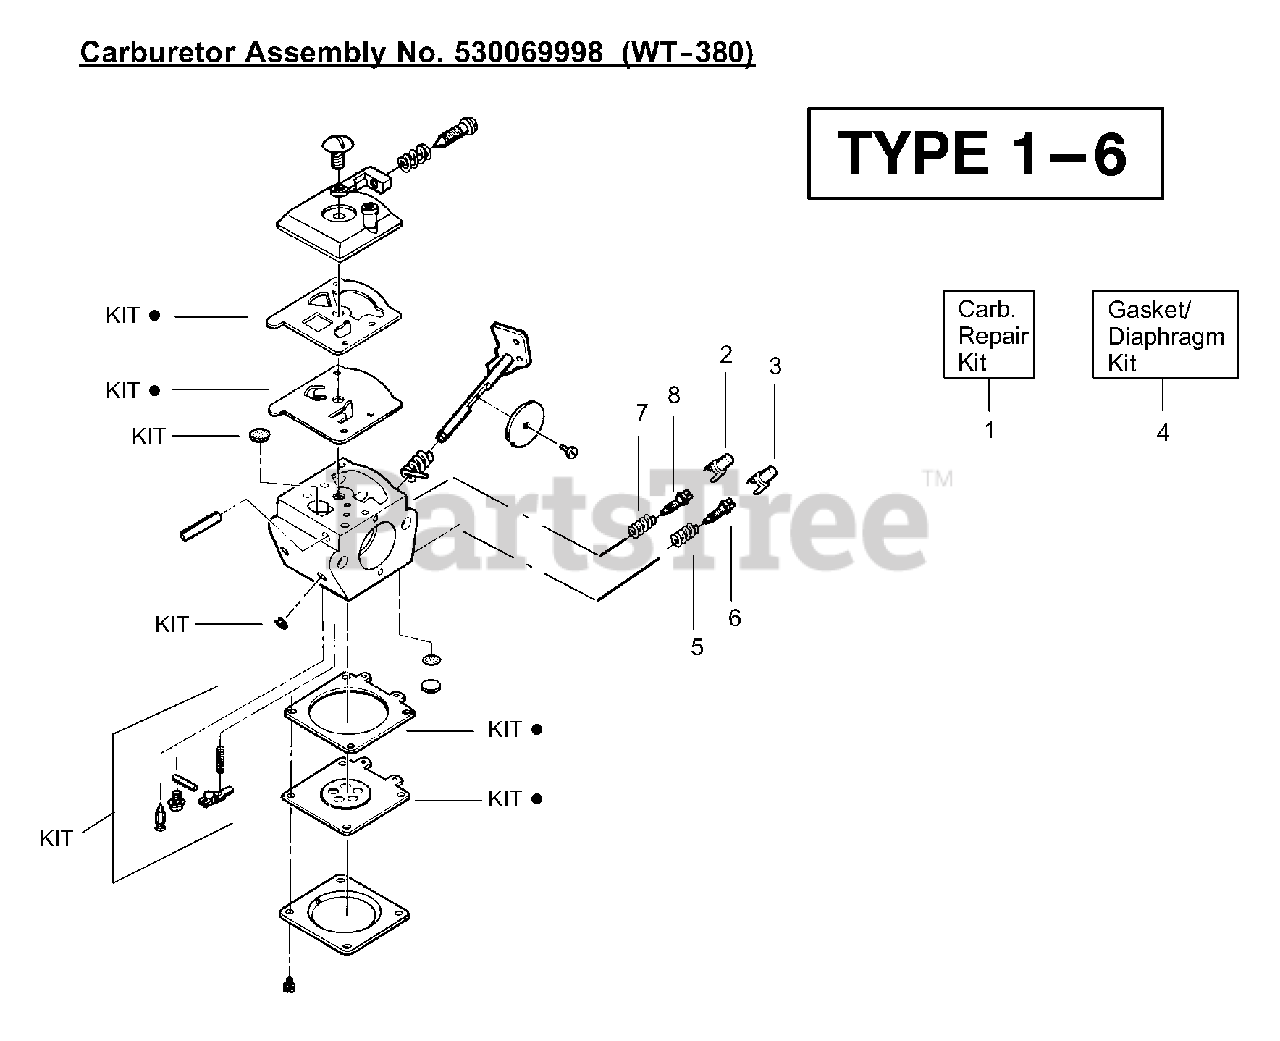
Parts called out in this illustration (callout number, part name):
1	Carburetor Repair Kit
2	Limiter Cap (High-Red)
3	Limiter Cap (Low-Blue)
4	Gasket/Diaphragm Kit
5	Needle Spring-Low Speed
6	Needle-Low Speed
7	Needle Spring-High Speed
8	Needle-High Speed
530069998	Carburetor Assembly - WT380
